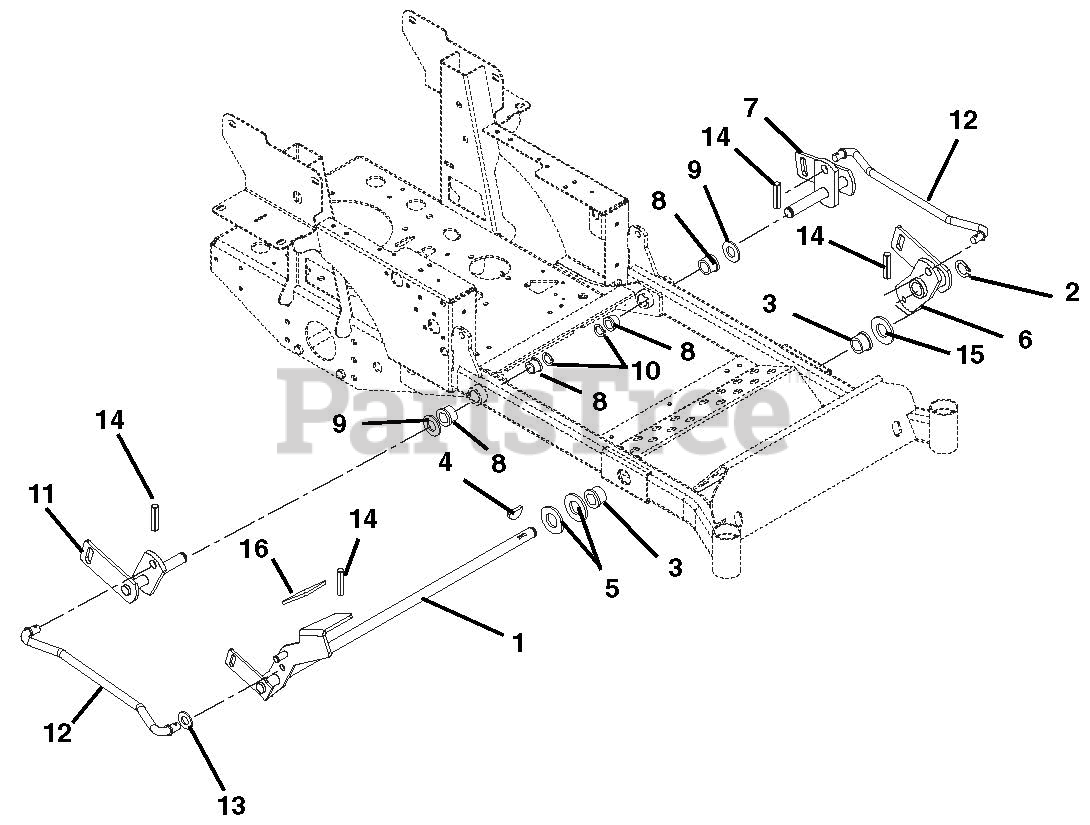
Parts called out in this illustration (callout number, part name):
1	Weldment, Mechanical Deck Lift
2	Ring, Retaining External 1.00 x .078
3	Bushing, Flange Nylon 1.020 x 1.385 x .75 x 1.75
4	Key, Woodruff .25 x 1.00
5	Washer, Flat Steel 1.062 x 2.0 x .134
6	Weldment, Left Hand Mower Lift Arm
7	Weldment, Left Hand Rear Mower Lift Arm
8	Bushing, Flange Nylon .762 x 1.0 x .580 x 1.48
9	Washer, Hardened Steel .758 x 1.23 x .031
10	Ring, Retaining External .689 x .077
11	Weldment, Right Hand Rear Mower Lift Arm
12	Rod, Lift Assist
13	Washer, Flat Steel .630 x 1.25 x .062
14	Pin, Roll .25 x 1.25 Stainless Steel
15	Washer, Hardened Thrust 1.00 x 1.55 x .03
16	Grip, Pedal
